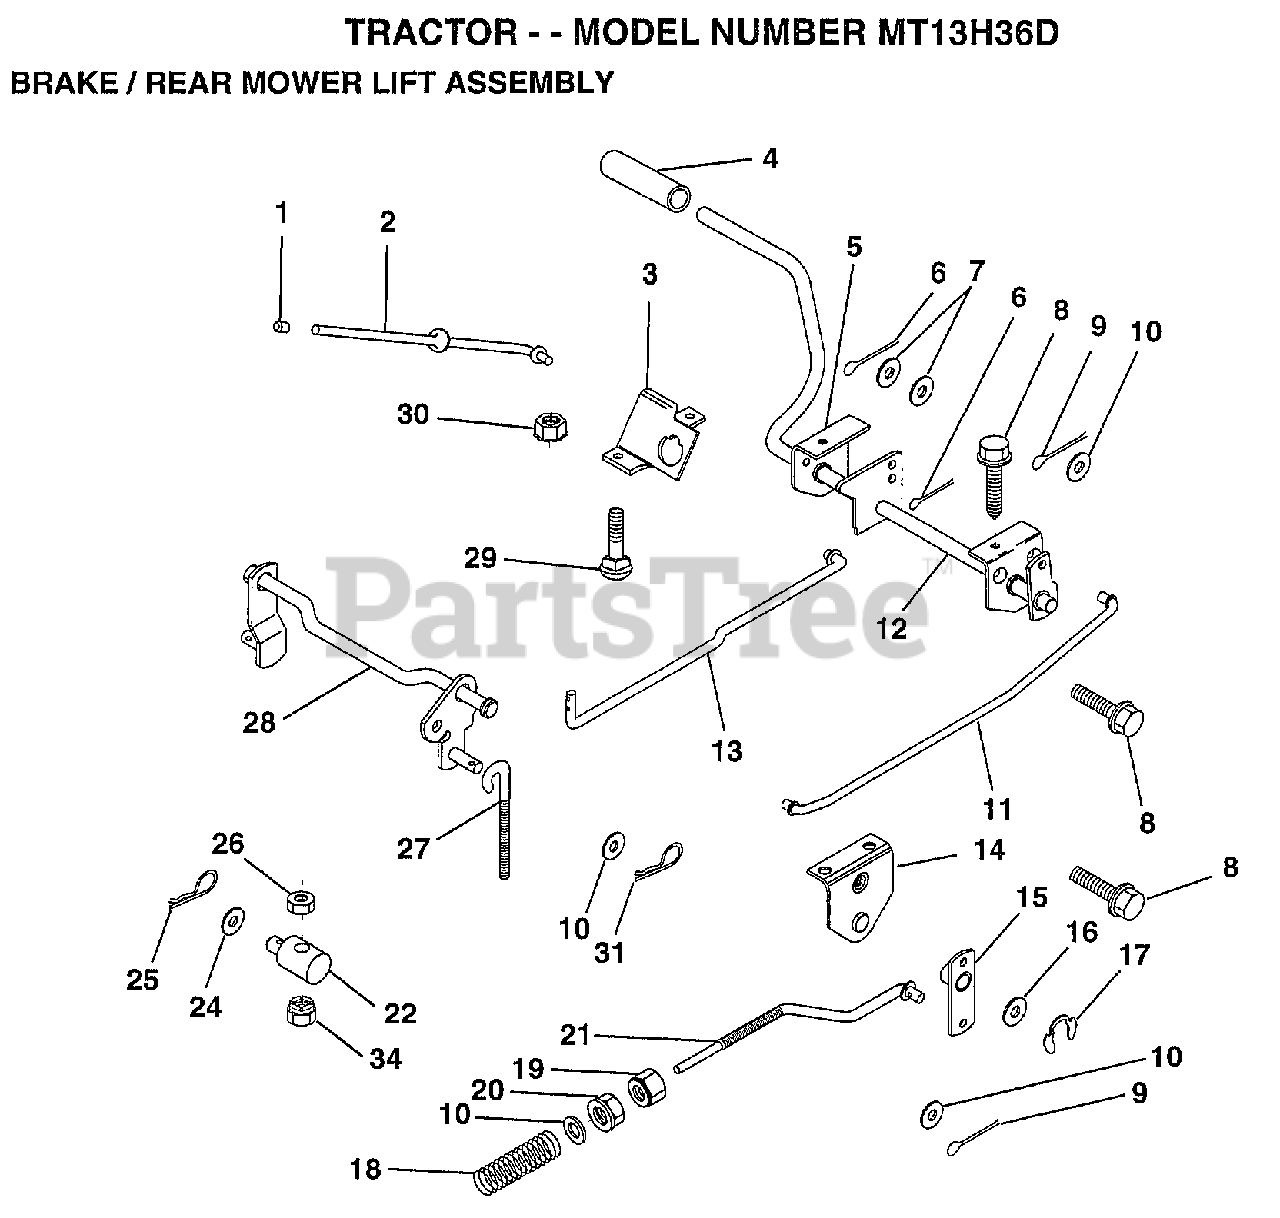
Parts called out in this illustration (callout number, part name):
1	PLUNGER CAP T
2	"ROD,PARK BRAKE"
3	"BRKT,PARK BRAKE"
4	"COVER,PEDAL"
5	"BRKT,CLU PEDAL LH"
7	WASHER
8	SCREW LT
9	COTTER PIN
10	WASHER
11	"ROD,FRT BRAKE"
12	PEDAL ASM CL/BK36
13	"ROD,CLUTCH"
14	"BRKT,LIFT SHAFT"
15	PVT BRAKE ARM ASM
16	WASHER T
17	KLIP RING
18	SPRING ROD BRAKE
19	NUT
20	NUT
21	ROD.BRAKE.HYDRO
22	TRUNNION.LIFT.
24	WASHER
25	SPRING.RETAINER
26	LOCKNUT
27	LINK, THREADED
28	LIFT ASM MOW REAR
31	RETAINER.SPRING
